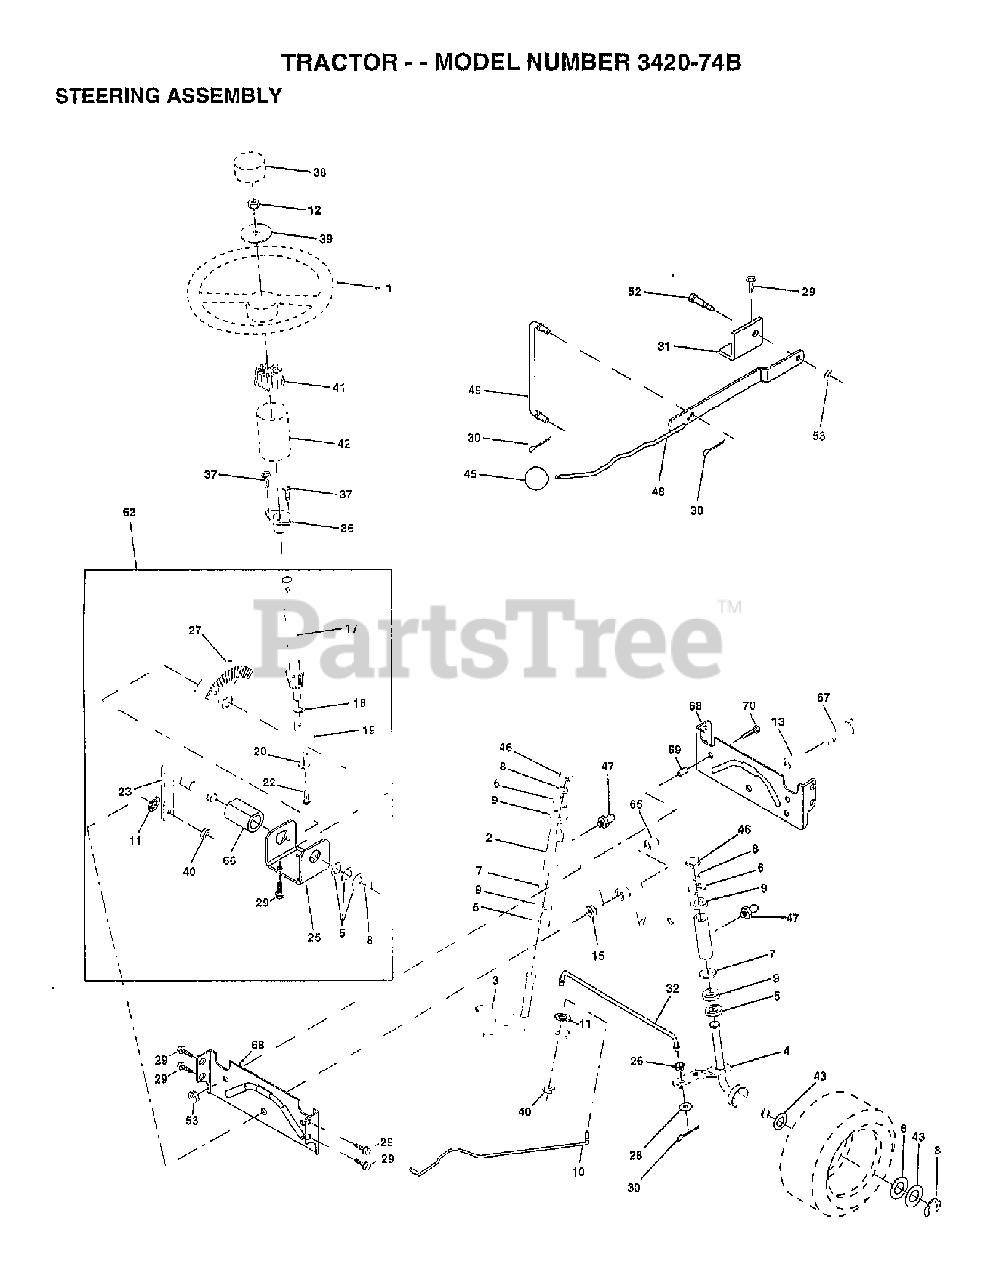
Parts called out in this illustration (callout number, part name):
1	Steering Wheel
2	Half Axle Assembly, Welded
3	SPINDLE.ASM.LH
4	SPINDLE ASM RH
5	WASHER THRUST
8	RETAINING RING LT
9	BEARING.STEERING.COLUMN
10	DRAGLINK-STAMPED
11	WASHER, LOCK 3/8
12	NUT.HEX.1/2-20
13	BEARING AXLE
15	LOCK NUT
17	STEERING SHAFT
18	THRUST WASHER
19	SHAFT,SUPPORT
20	WASHER
23	SHAFT,PITMAN
25	BRACKET STEERING
26	BUSHING STEERING
27	GEAR.SECTOR
28	WASHER
30	COTTER PIN
36	BUSHING STRG 3/4
37	SCREW.TT.#10-32X.5.3/8.FLANGE
38	INSERT STR WHL
40	NUT
46	CAP.SPINDLE.BLACK
47	ZERK.GREASE.TAPERED
53	LOCKNUT
62	STEERING KIT
65	SPACER AXLE
66	BEARING ARM
67	BOLT.HEX.FINISHED.5/8
68	AXLE, BRACE
69	SPACER BRACE AXLE
